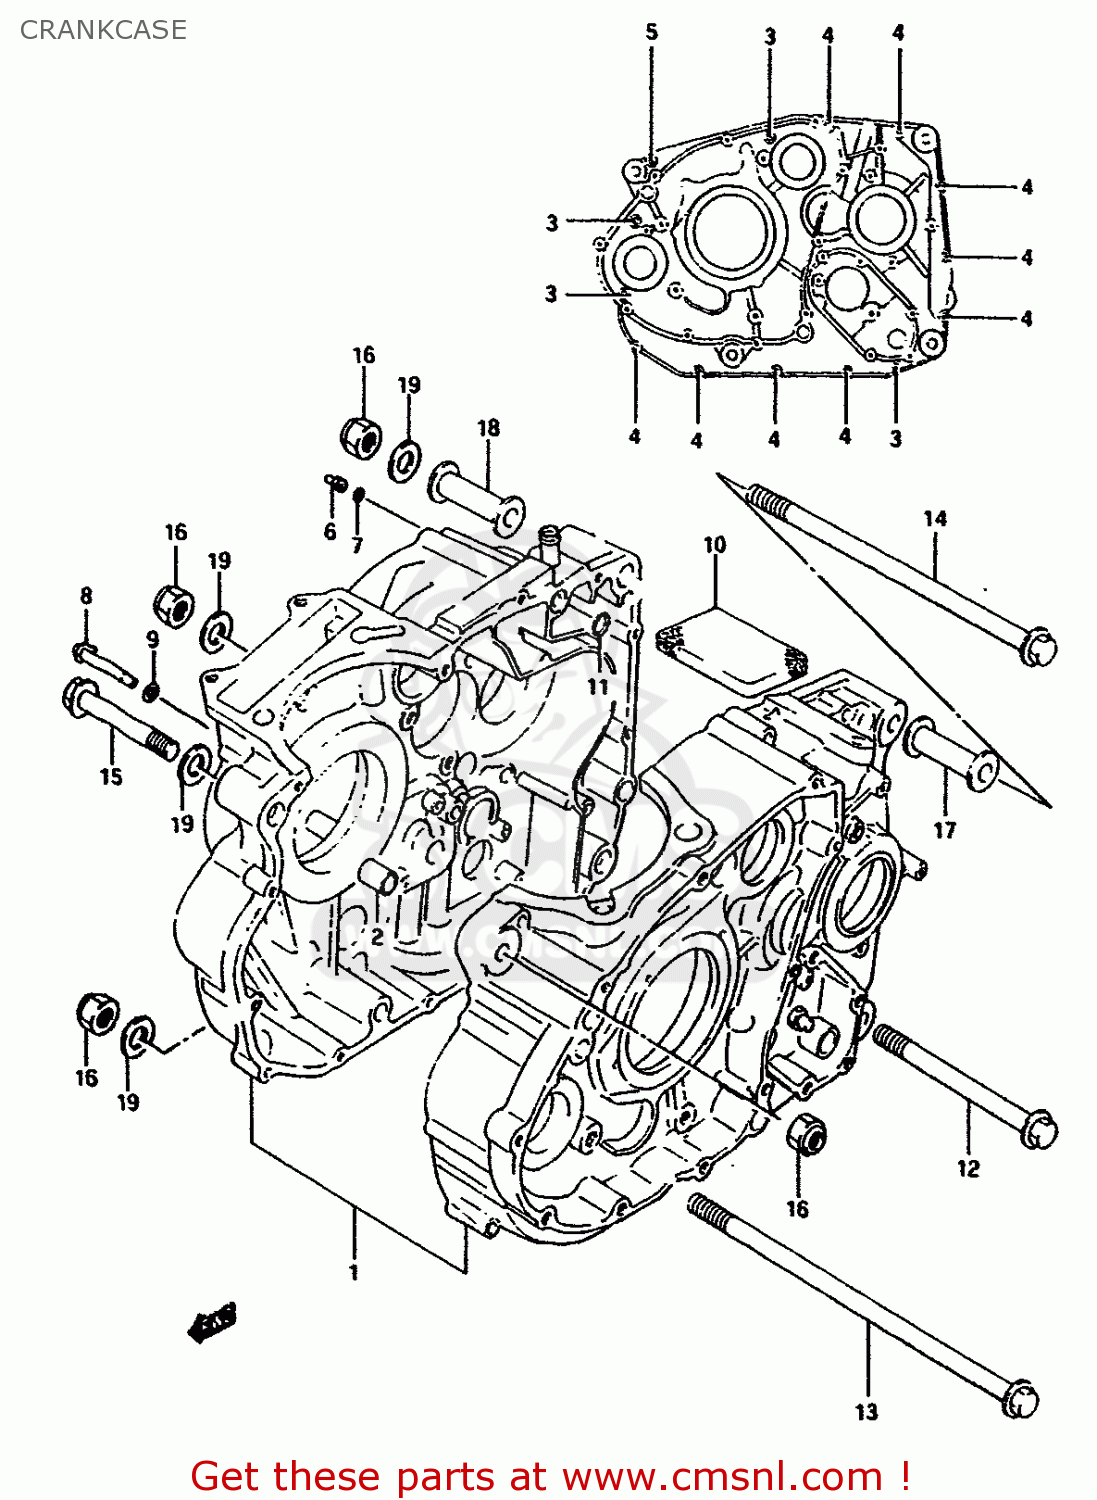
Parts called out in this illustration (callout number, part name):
1	CRANKCASE SET
2	PIN
3	BOLT (6X60)
4	BOLT 6X40
5	BOLT 6X30
6	JET(12)
7	O RING(D:1.2,ID:4)
8	PIPE,PISTON COOLING
9	O-RING
10	SEPARATOR,OIL BREATHER
11	O-RING
12	BOLT(10X130)
13	BOLT 10X230
14	BOLT(10X235)
15	BOLT(10X80)
16	NUT (10MM)
17	SPACER,ENG MTG(L:55)
18	SPACER,ENGINE MOUNT(L:65)
19	WASHER 10MM
